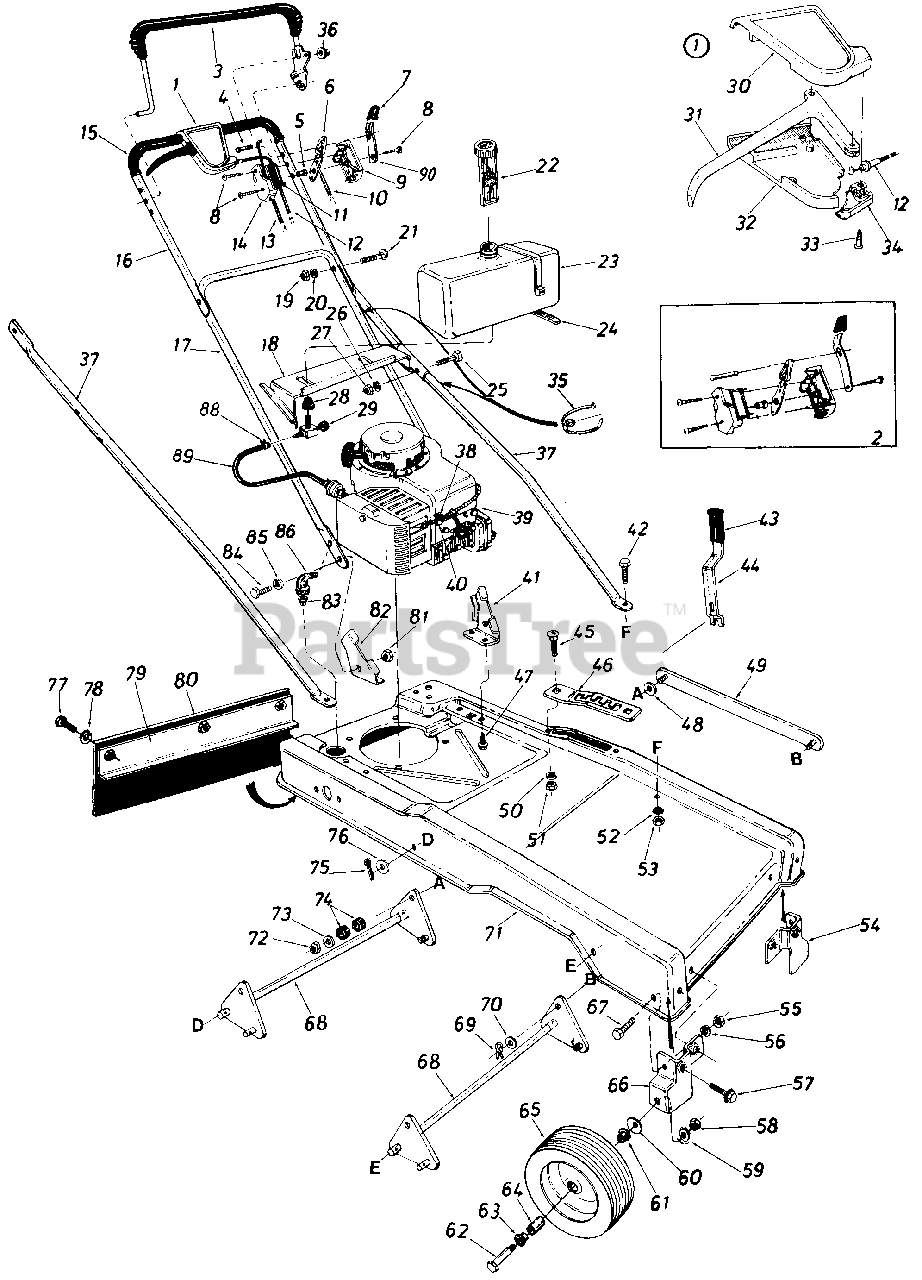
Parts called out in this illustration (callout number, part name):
1	Clutch Control Housing Comp.
2	Control Housing Comp.
3	Control Handle Ass'y.
5	Control Disc Pin
6	Throttle Control Lever
7	Spring Lever Knob
8	Truss Mach. Hi-B 0 Tap Scr. #12 x 1.50" Lg.
9	Control Panel Half
10	Throttle Control Wire 43" Lg.
11	Control Label-Throttle
12	Self-Propelled Cable 50" Lg.
13	Drive Clutch Cable-46" Lg.
14	Clutch Panel Half
15	Grip 22" Lg.
16	Upper Handle (Painted)
17	Lower Handle (Painted)
18	Gas Tank Mounting Brkt.
19	Hex Nut 5/16-18 Thd.
20	L-Wash. 5/16" I.D.
21	Carriage Bolt 5/16-18 x 1.50" Lg.
22	Ga.s Gauge 13/4-6 x 5.50" Lg.
24	Cable Tie 30.6" Lg.
25	Hex Bolt 5/16-24 x 1.25" Lg.
26	L-Wash. 5/16" I.D.
27	Hex Nut 5/16-24 Thd.
28	Bushing-Gas Tank
29	Fuel Shut-Off Valve w/Screen
30	Control Cover Half-Upper
31	Control Lever
32	Control Cover Half-Lower
33	Flat "C" Sunk Hd. Tap Scr. #10 x .75" Lg.
34	Cable Mounting Cap
35	Cable Tie
37	Strut .75" O.D. x 43.44" Lg.
38	Hex Sems Scr. #10-32 x .62" Lg.
39	Engine-5 H.P.
40	Casing Clamp
41	Handle Mount Brkt.-L.H.
42	Hex Bolt 5/16-18 x .75" Lg.*
44	Lift Handle
45	Carriage Bolt 5/16-18 x .62" Lg.
46	Lift Handle Support Brkt.
47	Hex Wash. Hd. B-Tap Scr. 5/16-1 8 x .50
48	Fl-Wash. .406" I.D. x 1.25" O.D.
49	Connecting Link Ass'y.
50	L-Wash. 5/16" I.D.*
51	Hex Nut 5/16-18 Thd.*
52	L-Wash. 5/16" I.D.*
53	Hex Nut 5/16-18 Thd.*
54	Wheel Brkt. Ass'y.-L.H.
55	Hex Nut 5/16-18 Thd.*
56	L-Wash. 5/16" I.D.*
57	Hex Sems Bolt 5/16-18 x .75" Lg.
58	Hex Cent. L-Nut 3/8-16 Thd.
59	L-Wash. 3/8" I.D.*
60	Bell-Wash. .400" I.D. x .88" O.D.
61	Flanged Ball Brg. 3/8" I.D.
62	Hex Bolt 3/8-16 x 2.00" Lg.*
63	Flanged Ball Brg. .501" I.D.
64	Spacer .375" I.D. x .505" O.D. x 1" Lg.
66	Wheel Brkt. Ass'y.-R.H.
67	Hex Sems Bolt 5/16-18 x .75" Lg.
68	Lift Brkt. Shaft Ass'y.
69	Intern. Cotter Pin 5/16" Dia.
70	Fl-Wash. .385" I.D. x .88"
71	Hi-Wheel Frame
72	Hex Ins. L-Nut 3/8-24 Thd.
73	Fl-Wash. .385" I.D. x .88"
74	Rubber Wash. .33" I.D. x .87" O.D.
75	Cotter Pin 1/8" Dia. x 1" Lg. *
76	Fl-Wash. .51" I.D. x 1.0"
77	Hex Bolt 1/4-20 x .62" Lg.*
78	L-Wash. 1/4" I.D.*
79	Retaining Strip Ass'y. 3" x 15" Lg.
80	Rear Flap 7.5 x 20" Lg.
81	Hex Nut 3/8-16 Thd.*
82	Handle Mount Brkt.-R.H.
83	Part of Engine
84	Hex Bolt 3/8-16 x .75" Lg.*
85	L-Wash. 3/8" I.D.*
86	90 Deg. Elbow Male to Female 3/8
88	Hose Clamp-.406" Dia.
89	Fuel Line 15" Lg.
90	Lockout Lever
